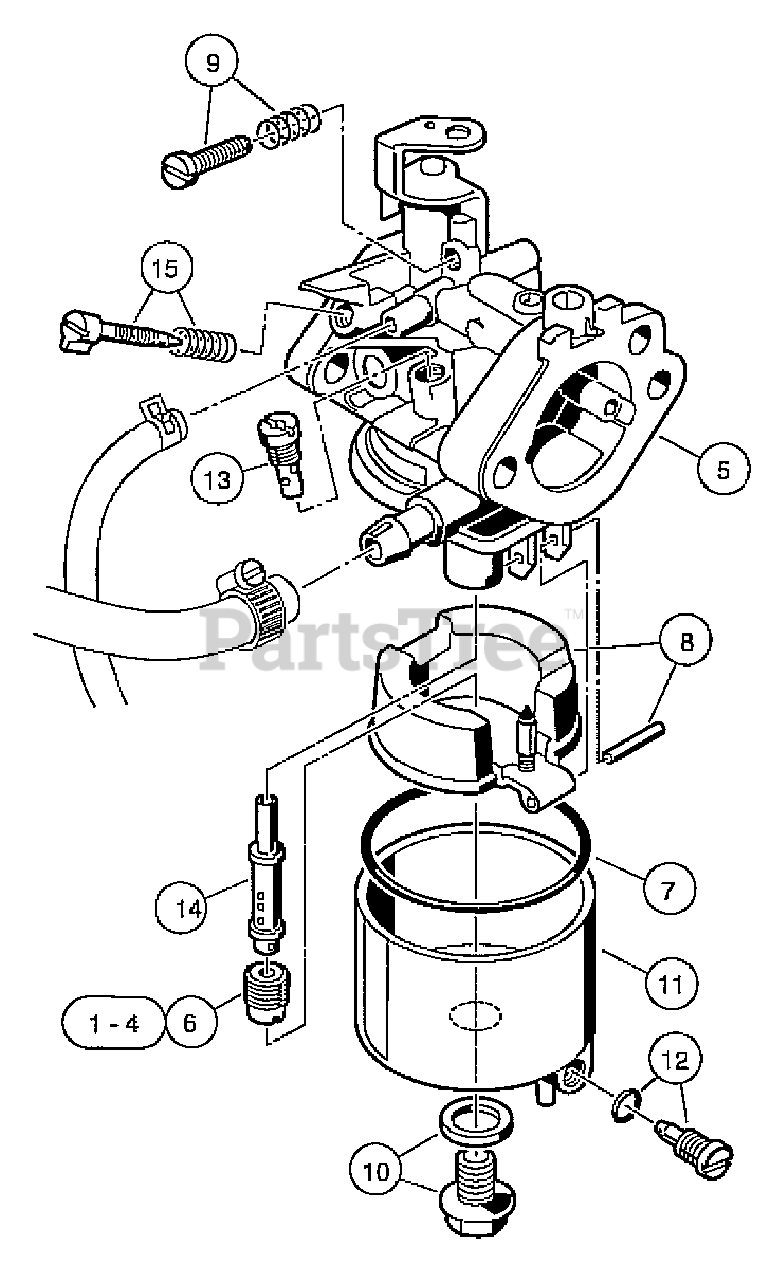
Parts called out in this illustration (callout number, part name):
1-4	Jet, Altitude, # 72
1-4	Jet, Altitude, # 75
1-4	Jet, Altitude, # 78
1-4	Jet, Altitude, # 80
5	Carburetor Assembly, FE2900
6	Jet, Altitude, # 82
7	Gasket, Carburetor Bowl OHV
8	Float Assembly
9	Screw Assembly
11	Chamber Assembly, Float
12	Screw Assembly
13	Jet, #40 Pilot
14	Nozzle, Main
15	Assembly, Pilot Air Screw
